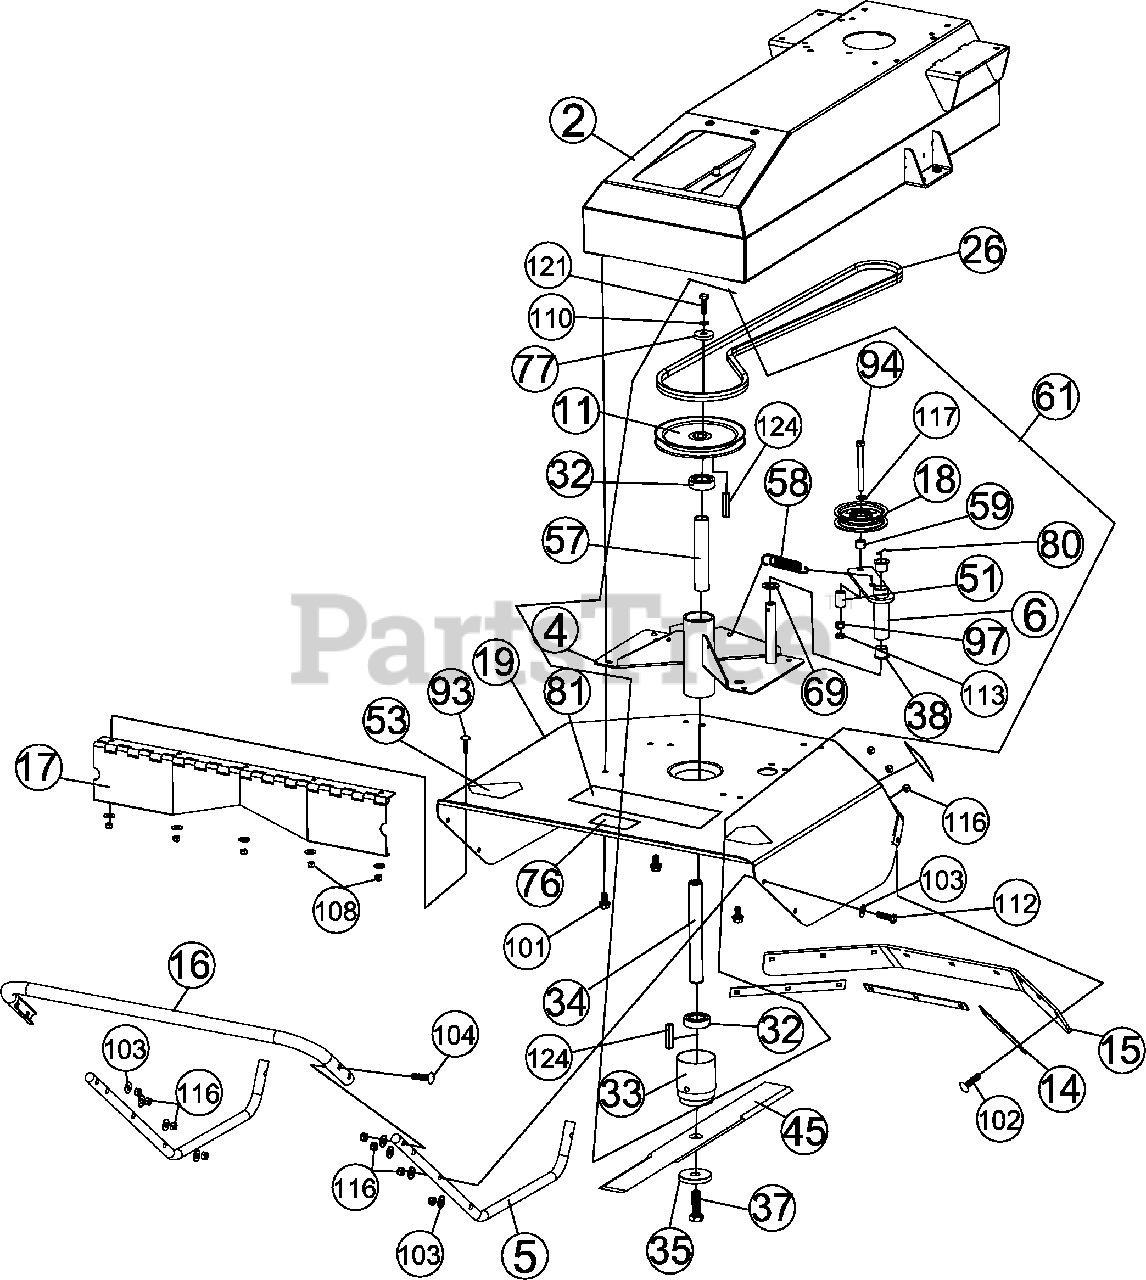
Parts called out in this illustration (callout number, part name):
2	BASE ENGINE BC26 FIXED WA W/LABELS
4	BRACKET DECK MOUNT WA BC
5	SKID BC26
6	ARM IDLER DECK WA BC
11	PULLEY 7" OD X 1.00" BORE
14	PLATE CLAMP SKIRTING BC26
15	DEFLECTOR RUBBER BC26
16	BAR GUARD BC26
17	HINGE DEFLECTOR BC26
18	PULLEY IDLER 4.00" OD X 3/8" BORE
19	DECK WA BC26
26	BELT 6972 POWERATED
32	BEARING 1.00" SEALED PRESS IN
33	ADAPTER BLADE WA BC26
34	SHAFT BLADE BC2600
35	WASHER BLADE BC26
37	SCREWCAP 9/16"-18 X 1 3/4" GR 8
38	BUSHING PIVOT LIFT
45	BLADE 26" FLAT BC26
51	BUSHING PIVOT FRAME AE
53	LABEL DANGER
57	SPACER SPINDLE BEARING BC2600
58	SPRING IDLER
59	TUBE PIVOT IDLER VQ
61	SPINDLE ASSY BC26 FIXED
69	WASHER .765" ID X 1.25" OD X .06"
76	LABEL DANGER FLYING DEBRIS
77	WASHER 1.5 OD X .453 ID X .25 THK
80	PIN COTTER 1/8" X 1"
81	LABEL OUTBACK BC26 MECH
93	BOLT CARRIAGE 1/4"-20 X 3/4" ZP
94	SCREWCAP 3/8"- 16 X 3 3/4" HCS ZP
97	NUT LOCK 3/8"-16 HEX
101	SER HEX WSHR FLNG SCR .375" - 16 X .75"
102	BOLT CARRIAGE 5/16"-18 X 1" ZP
103	WASHER 5/16" FLAT ZP
104	BOLT CARRIAGE 5/16"- 18 X 1 1/4" ZP
108	NUT LOCK 1/4"-20 HEX ZP
110	WASHER LOCK 3/8" S/T MED
112	SCREWCAP 5/16"-18 X 1 1/2" HCS ZP
113	NUT LOCK 3/8"- 16 LT WT TH ZP
116	NUT LOCK 5/16"-18 HEX ZP
117	WASHER 3/8" SAE
121	SCREWCAP 3/8"-16 1 1/4" HCS ZP
124	KEY 1/4" SQ X 3/4"
